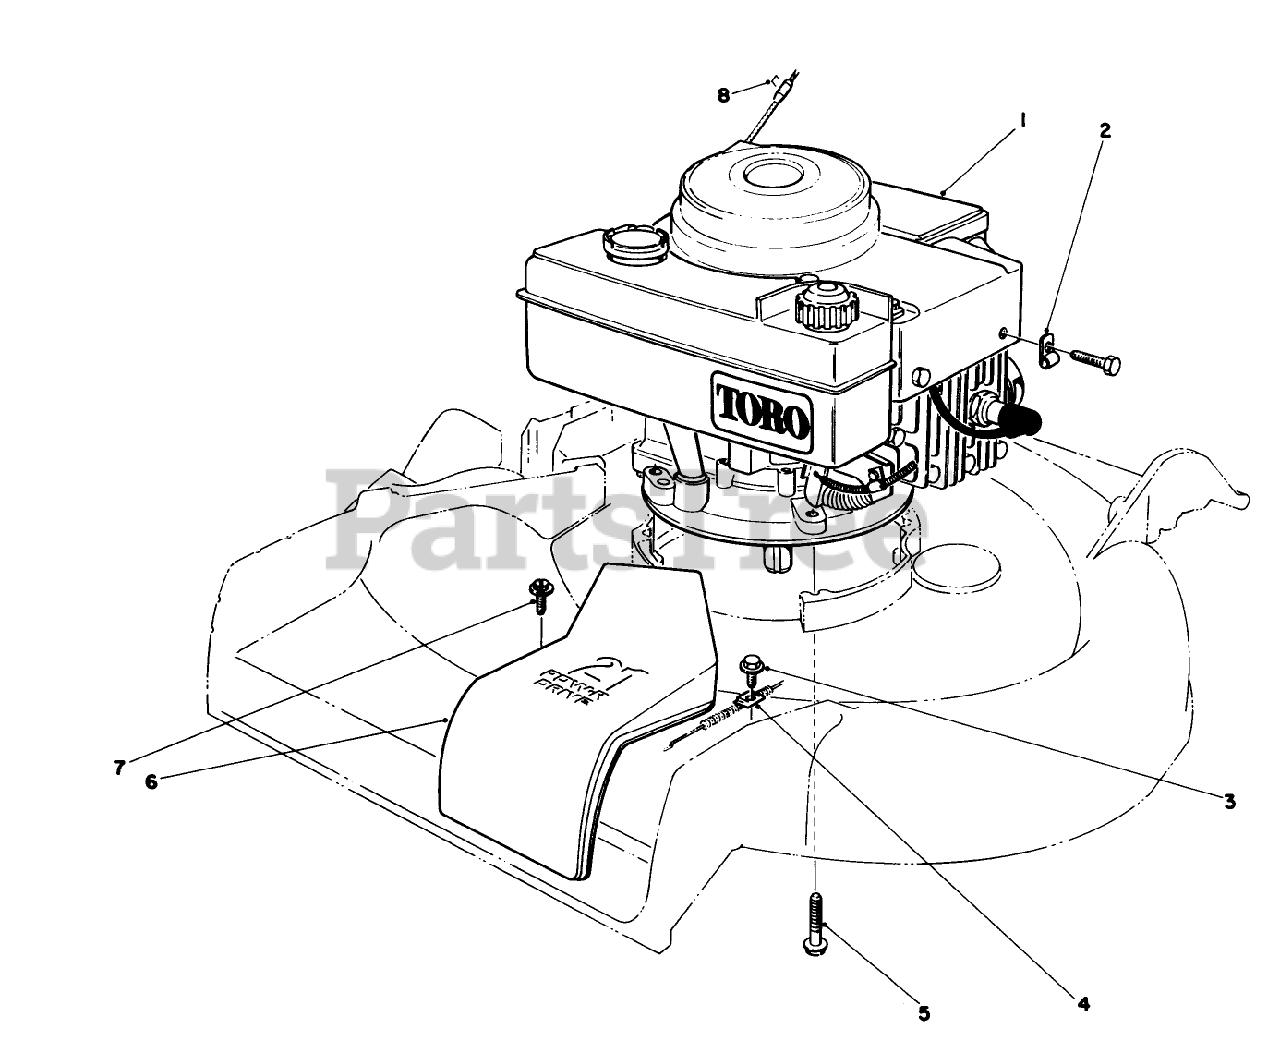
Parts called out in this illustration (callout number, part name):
1	Engine
3	SCREW-THD ROLL, HWH
5	3/8-16 X 2-3/4 CAPSCR
6	BELT COVER 21" S D
7	SCREW
8	Stable
